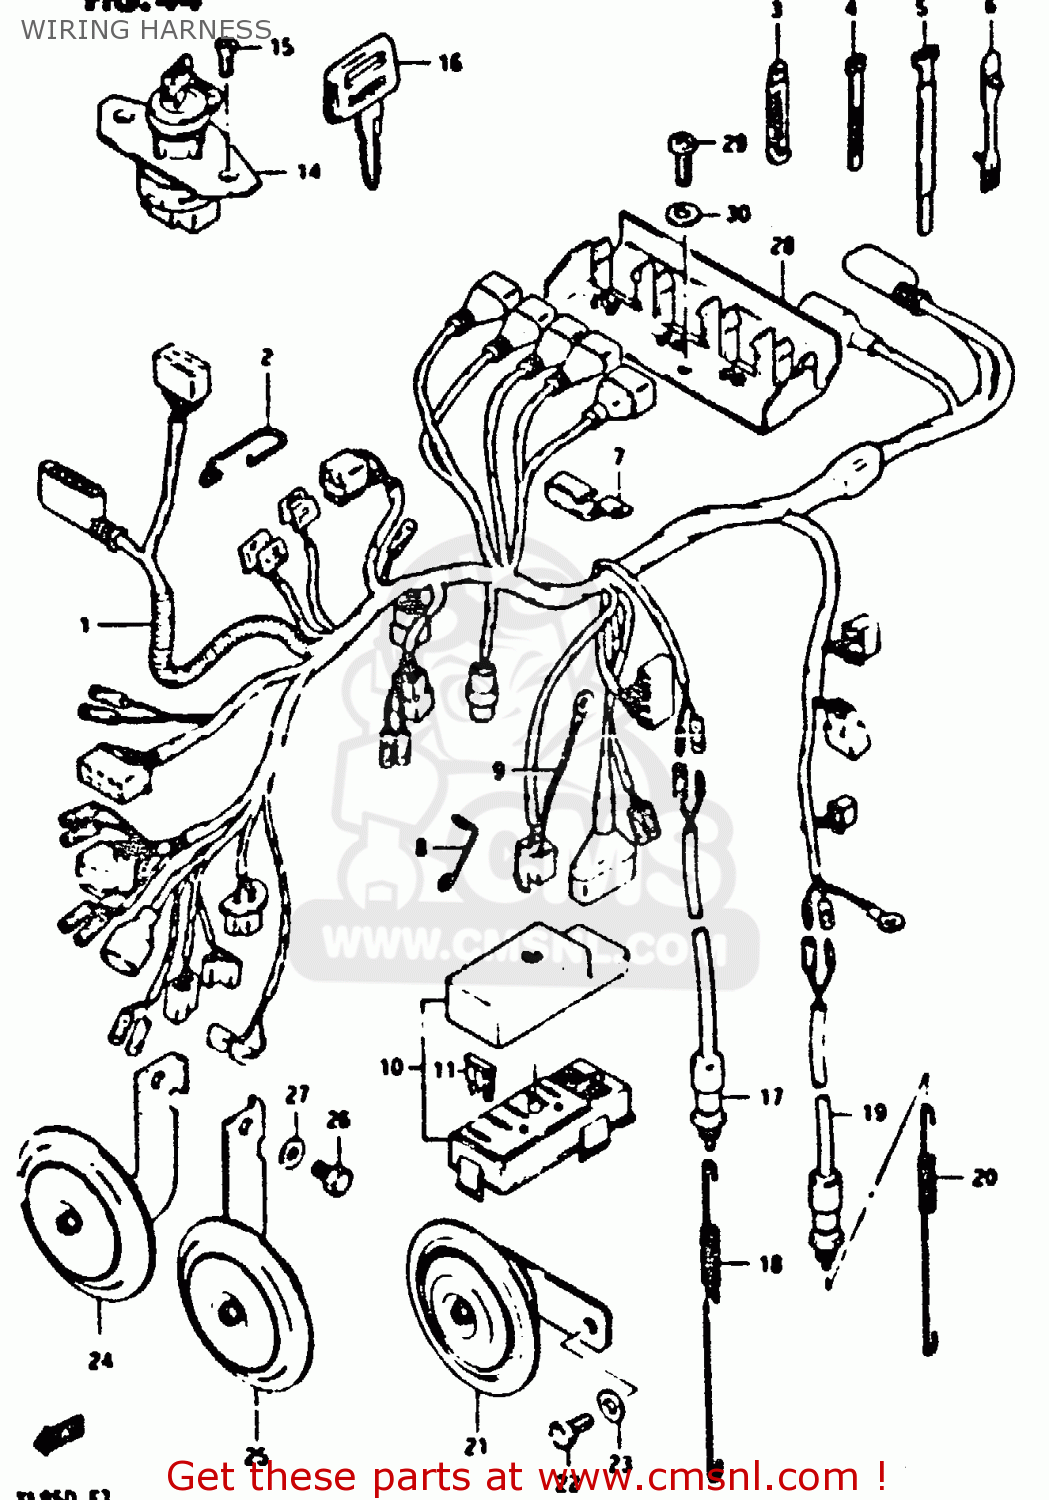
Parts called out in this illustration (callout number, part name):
1	HARNESS,WIRING
2	GUIDE,WIRING HARNESS
3	CLAMP
4	CLAMP(L:80)
5	CLAMP
6	CLAMP,L:88
7	CLAMP
8	GUIDE,WIRING HARNESS
9	WIRE
10	BOX ASSEMBLY,FUSE
11	FUSE(10A)
12	SCREW
13	WASHER
14	SWITCH ASSEMBLY,IGNITION
15	SCREW
16	KEY,BLANK
17	SWITCH ASSEMBLY,STOP LAMP
18	SPRING
19	SWITCH ASSEMBLY,SIDE STAND
20	SPRING
21	HORN ASSY
22	BOLT 8X12
23	WASHER
24	HORN ASSEMBLY,HIGH PITCH
25	HORN ASSEMBLY,LOW PITCH
26	BOLT 8X12
27	WASHER
28	HOLDER, COUPLER
29	SCREW
30	WASHER
